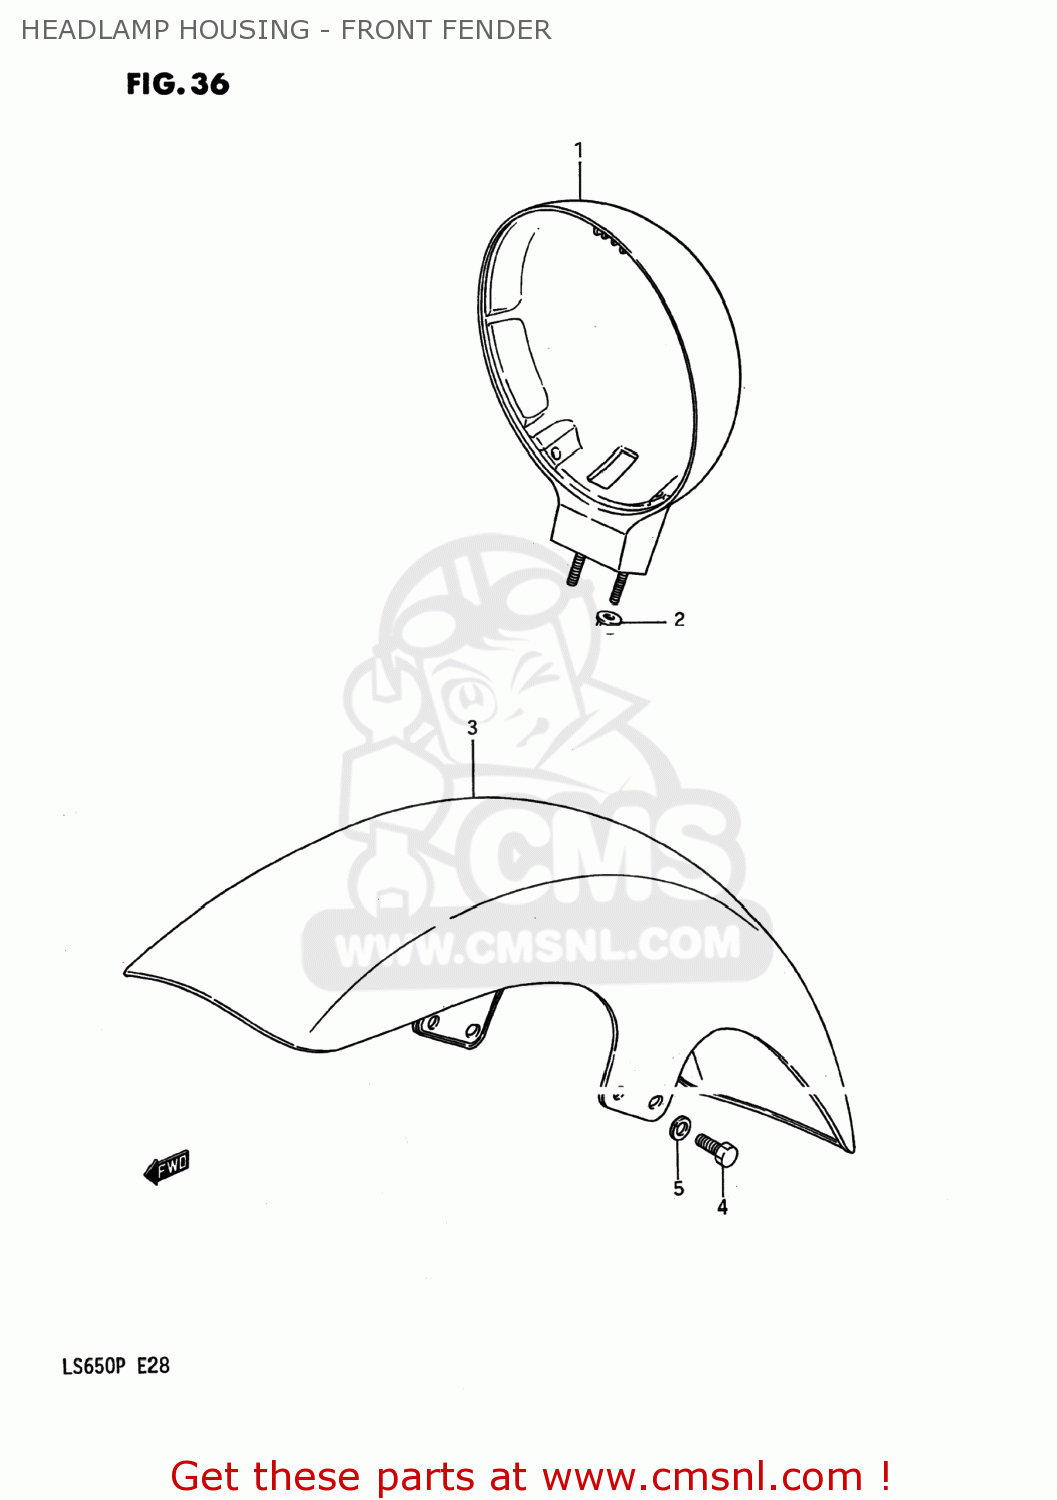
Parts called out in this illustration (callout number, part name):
1	HOUSING,HEADLAMP
2	NUT
3	FENDER,FRONT
4	BOLT
5	WASHER,LOCK
